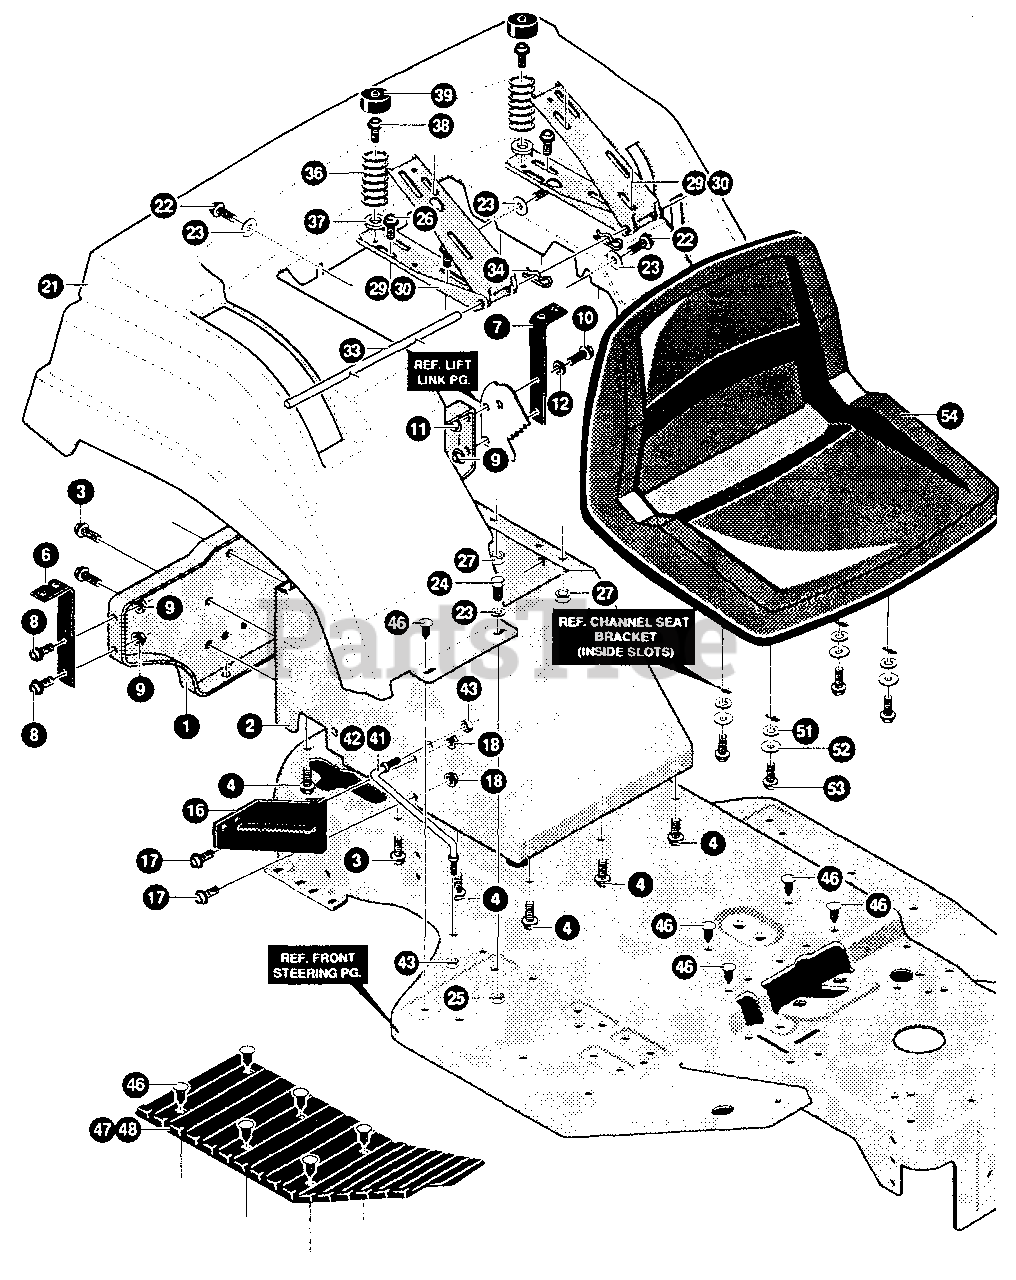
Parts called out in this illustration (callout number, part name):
1	SEAT SUPPORT ELECTRIC LIFT
2	SUPT, FENDER&SEAT ELECT/LIFT
3	SCREW, 5/16-18X .75 WAHHTAP
4	SCREW, 5/16-18X .50 WAHHTAP
6	SUPPORT FENDER RIGHT
7	SUPPORT FENDER LEFT
8	SCREW, 5/16-18X.75WDFLLK
9	NUT, 5/16-18 HXWDFLLK
10	SCREW, 1/4-20X .75 HHC
11	NUT, 1/4-20 WDFLWHIZ-LK
12	WASHER, FLAT .250X .56X.049
16	SUPPORT. SHIFT PLATE
17	SCREW, 5/16-18X.75WDFLLK
18	NUT, 5/16-18 HXWDFLLK
21	FENDER,EURO F-10 GT MOLD GREY
22	SCREW, 1/4-20X .75 WAHHTAP
23	WASHER, FLAT .281X1.00X.063PL
24	SCREW, 1/4-20X .75 HHC
25	NUT, 1/4-20 REGHEXCTRLK
26	SCREW, 5/16-18 HXWDFLLK
27	NUT 5/16-18 REGHEXCTRLK
29	CHANNEL SEAT RH
30	CHANNEL SEAT LH
33	ROD SEAT SUPPORT BRZN
34	PIN, HAIR .072 DIAX1.13LG
36	SPRING, SEAT 1.50ODX2.25LG
37	WASHER, FLAT .344X .69X.065
38	SCREW, 5/16-18X .75 WAHHTAP
39	COVER, SEAT SPRING 1.5IDX1.0LG
41	SUPPORT, FOOTREST STIFNR RH ZPL
42	SUPPORT, FOOTREST STIFNR LH ZPL
43	NUT, 5/16-18 REGHEXCTRLK
46	FASTENER, RATCHET BLACK
47	FOOT PAD, ASSYRH ERO W/ADH
48	FOOT PAD, ASSYLH ERO W/ADH
51	WASHER, FLAT .344X .69X.065
52	WASHER, HVSPTLK .328X.60X.09
53	SCREW, 5/16-18X .75 HHC
54	SEAT, W/SW HOLE
